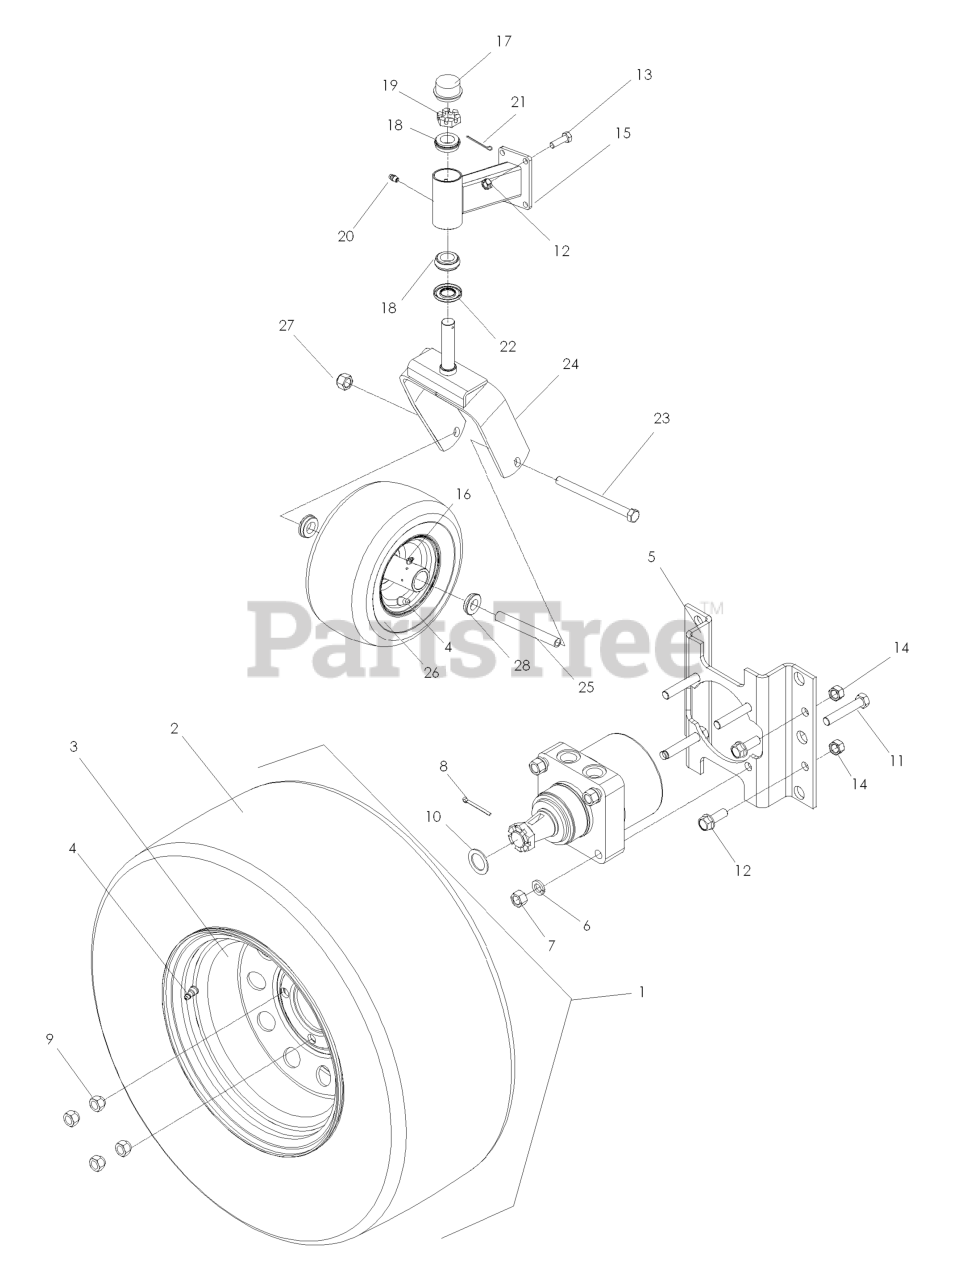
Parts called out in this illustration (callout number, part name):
1	WHEEL/TIRE.ASM.23X9.5-12.GREY
2	TIRE.TURF.MASTER.23X9.5-12
3	RIM.12X7.GRAY.+1".OFFSET.ZTR
4	VALVE STEM TR-412
5	MOTOR STANDOFF
6	WASHER 1/2" SPLIT LOCK
7	NUT HEX 1/2
8	PIN COTTER 4MM X 45MM
9	LUG NUT 1/2F
10	MACHINE BUSHING
11	HCS 1/2C X 2 3/4
12	NUT 7/16C CENTERLOCK
13	HCS 7/16-14 X 1 GR 5 ZD
14	NUT 1/2-13 HEX NYLOC ZD
15	CASTER ARM, ORG
16	ZERK 1/8 NPT
17	GREASE CAP
18	TAPERED ROLLER BRG
19	NUT 1"C HEX SLOTTED
20	ZERK
21	COTTER PIN 1/8 X 2
23	SCREW 1/2C X 7 1/2 HEX CAP
24	CASTER YOKE ORANGE
25	SPACER, CASTER
26	TIRE.ASSEM.13X5-6.SMOOTH.SILVE
27	NUT 1/2-13 HEX NYLOC ZD
28	BEARING RETAINER
